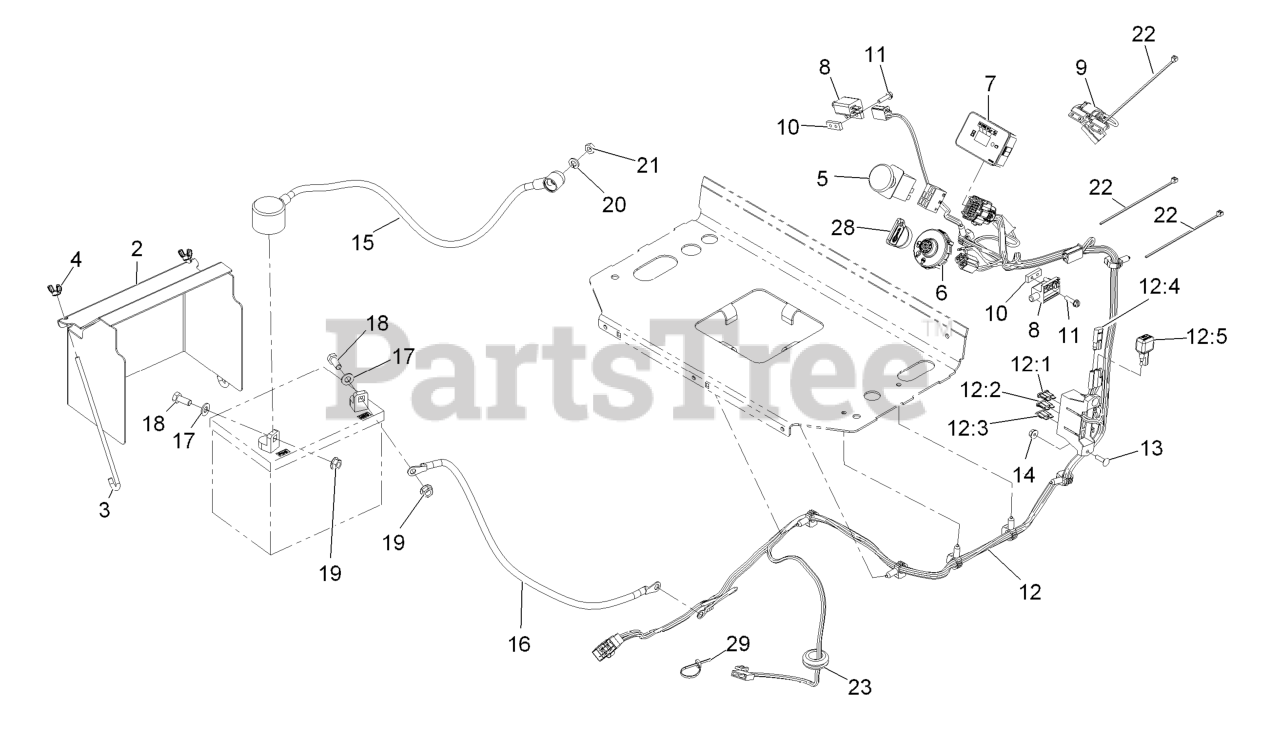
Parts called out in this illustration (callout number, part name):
2	COVER-BATTERY
3	BOLT-HOLDDOWN
4	WINGNUT
5	SWITCH-PTO, ON-ON
8	SWITCH-CLOSED, NORMALLY
9	HARNESS-SWITCH, REED
10	PLATE-TAPPED
11	SCREW-HWH
12	HARNESS-WIRE
12:1	FUSE-BLADE, 30 AMP
12:2	FUSE-BLADE, 25 AMP
12:3	FUSE-BLADE, 10 AMP
12:4	CAP-PLUG
13	SCREW-CARR
15	CABLE-BATTERY, POSITIVE
16	CABLE-BATTERY, BLACK
17	WASHER-PLAIN
18	SCREW-HH
19	NUT-HHF, SMOOTH
20	SCREW-HH
21	NUT-HEX
22	TIE-CABLE
23	GROMMET
28	KEY-IGNITION
29	TIE-CABLE
